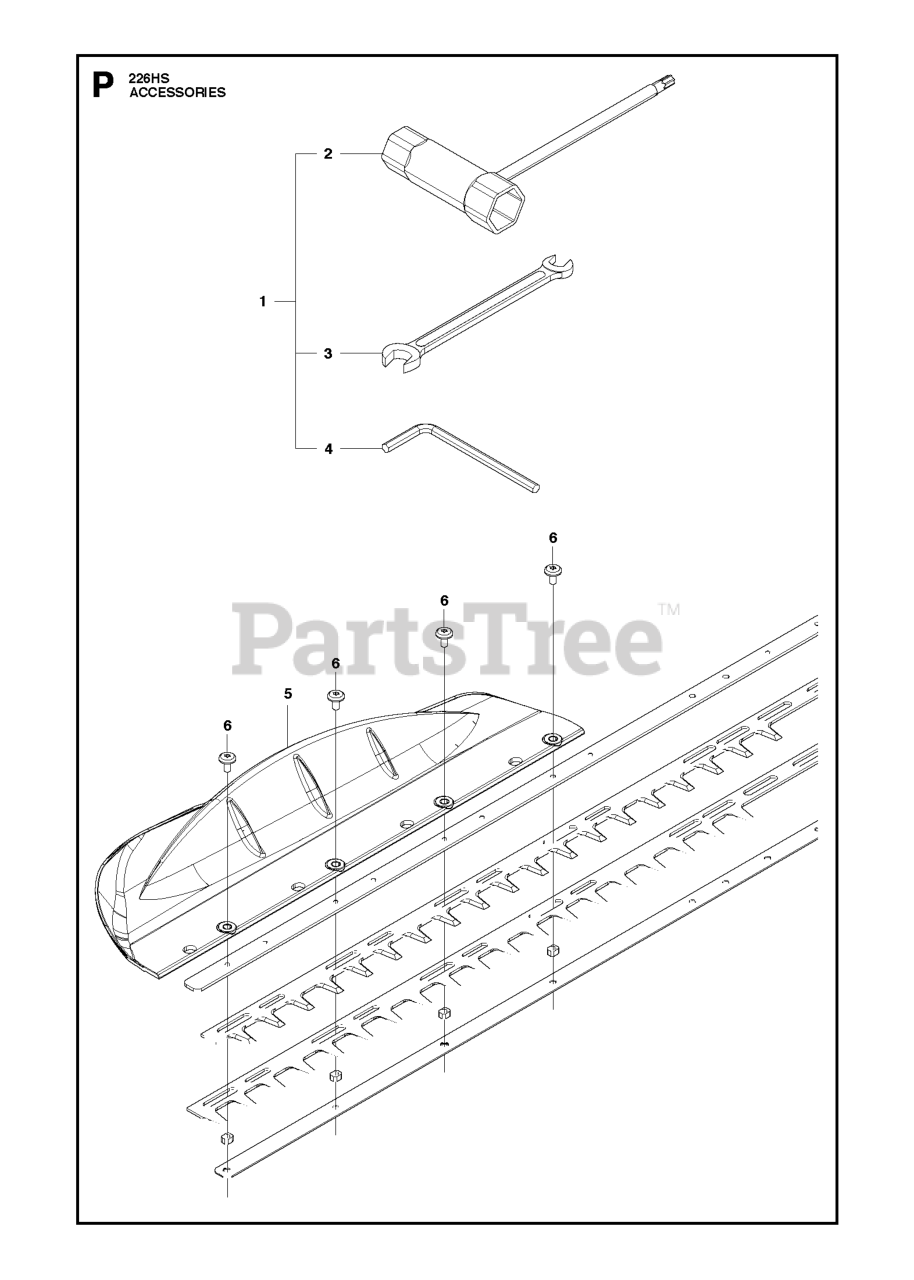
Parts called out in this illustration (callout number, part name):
2	SOCKET
3	WRENCH SPANNER
4	WRENCH
